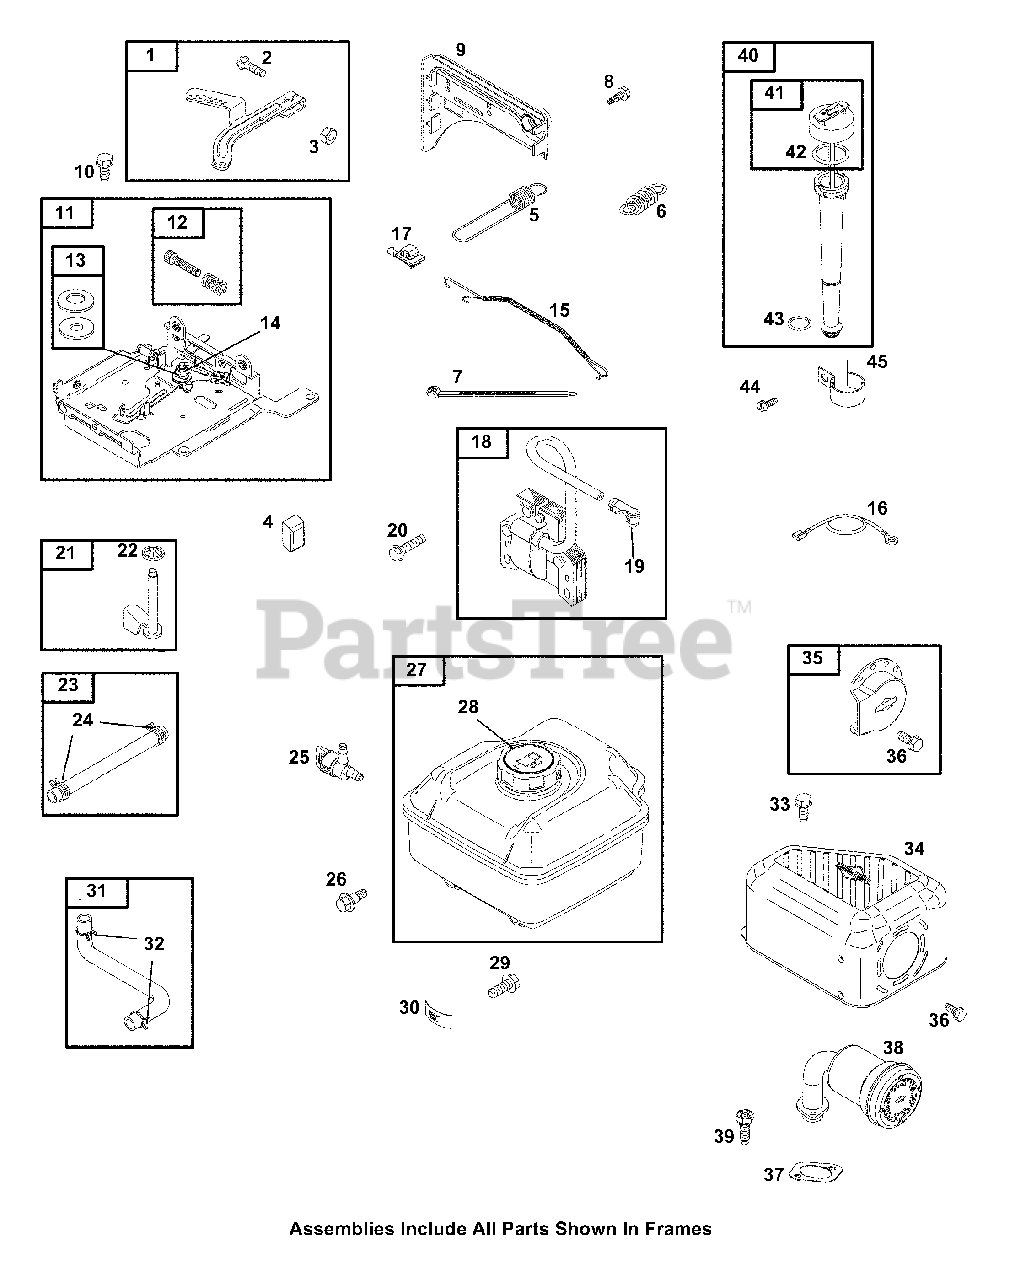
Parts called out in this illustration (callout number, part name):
1	Governor Lever
2	Bolt (Governor Control Lever)
3	Nut (Governor Control Lever)
4	Control Knob
5	Governor Spring
6	Governor Spring
8	Screw (Control Panel)
9	Control Panel
10	Screw (Control Bracket)
11	Control Bracket
12	Idle Speed Kit
13	Washer Set
14	Nut (Control Bracket)
15	Spring/Link (Mechanical Governor)
17	Switch-Stop
18	Armature-Magneto
19	Sparkplug Terminal
20	Screw (Magneto Armature)
21	Crank-Governor
22	Retainer-Governor Shaft
23	Fuel Line
24	Clamp-Hose
25	Valve-Shutoff
26	Screw (Fuel Tank)
27	Fuel Tank
28	Fuel Tank Cap
29	Screw (Fuel Tank)
31	Fuel Line (Molded)
32	Clamp-Hose
33	Screw (Muffler Guard)
34	Guard-Muffler
35	Deflector-Muffler
36	Screw (Muffler Deflector)
37	Gasket-Exhaust
38	Muffler-Exhaust
39	Screw (Muffler)
40	Dipstick/Tube Assembly
42	O-Ring Seal (Dipstick)
43	O-Ring Seal
44	Screw (Oil Fill Bracket)
45	Oil Fill Bracket
